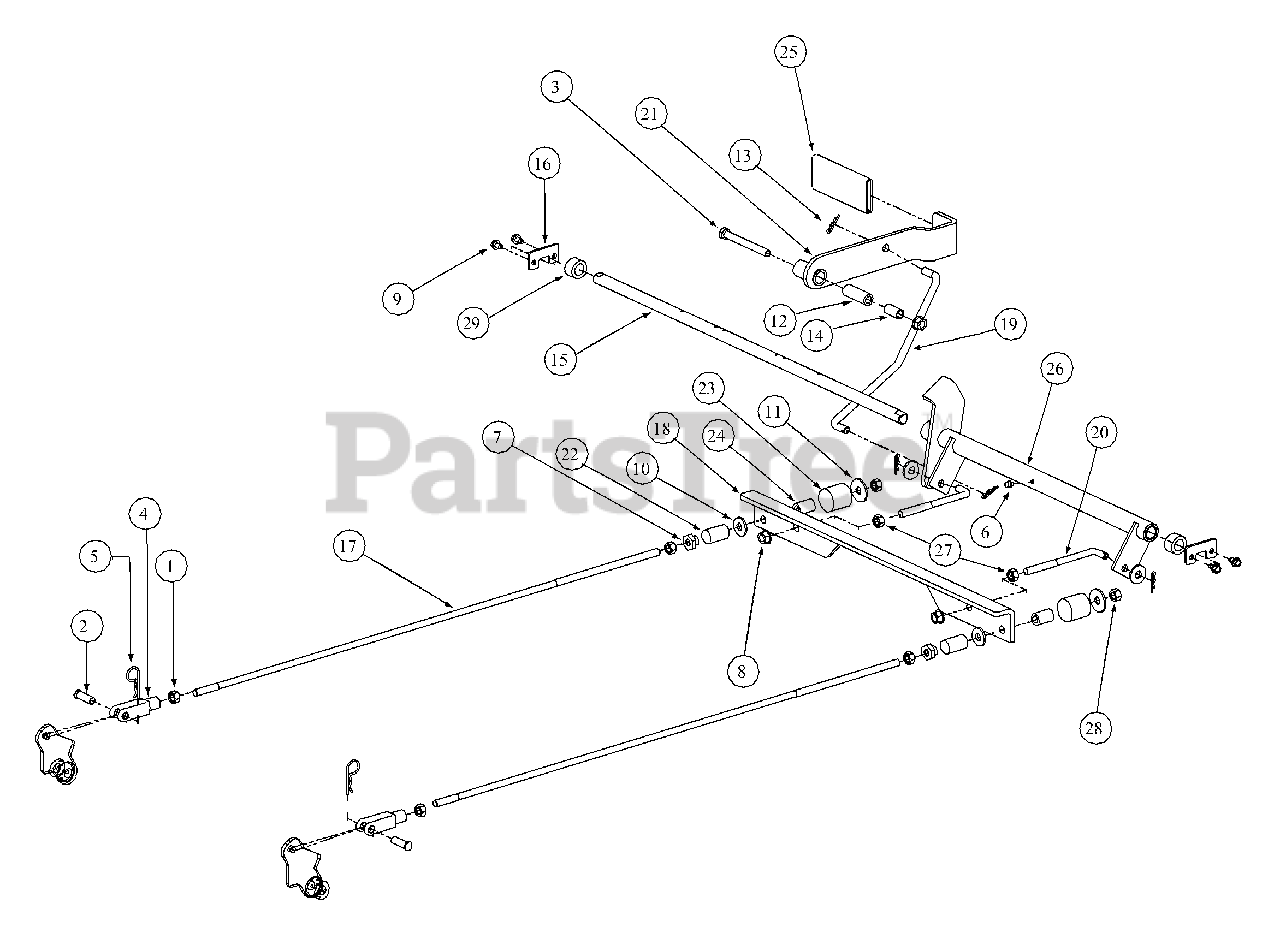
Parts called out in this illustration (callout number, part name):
1	Hex Nut, 3/8-16
2	Clevis Pin, 3/8 x 1, 1/8
3	HHCS, Standard, 3/8-16 x 3-1/2
4	Yoke, 3/8-16, Female
5	Hair Pin, 3/8"-1/2"
6	Grease Fitting, 1/4-28, 90°.
7	Shoulder Nut
8	Nut, Flange Lock, 3/8-16
9	Screw, TT, 1/4-20 x .5, Hex Index Washer
10	Flat Washer, .406 ID x 1.0 OD x .105
11	Flat Washer, .411 x 1.25 x .100
12	Spacer, .39 ID x .63 OD x 1.75
13	Hair Pin, INT .072 x 1.12 Lg.
14	Spacer, .375 x .50 x 1.02 Lg.
15	Mounting Shaft, Bellcrank
16	Holder Shaft, Park Brake
17	Rod Connector, 3/8 OD x 33
18	Brake Bracket
19	Rod Brake, Connect To Handle
20	Connecting Rod, 3/8 OD x 5.75
21	Weldment, Brake Handle
22	Brake Spring, Neutral
23	Brake Spring, Force
24	Brake Hose, Center
25	Grip, Park Brake
26	Weldment Hub, Brake Bearing
27	Jam Nut, 3/8-16
28	Lock Nut, Nylon Insert, 3/8-16
29	Shaft collar, .625 ID x 1" OD x .438 Lg
